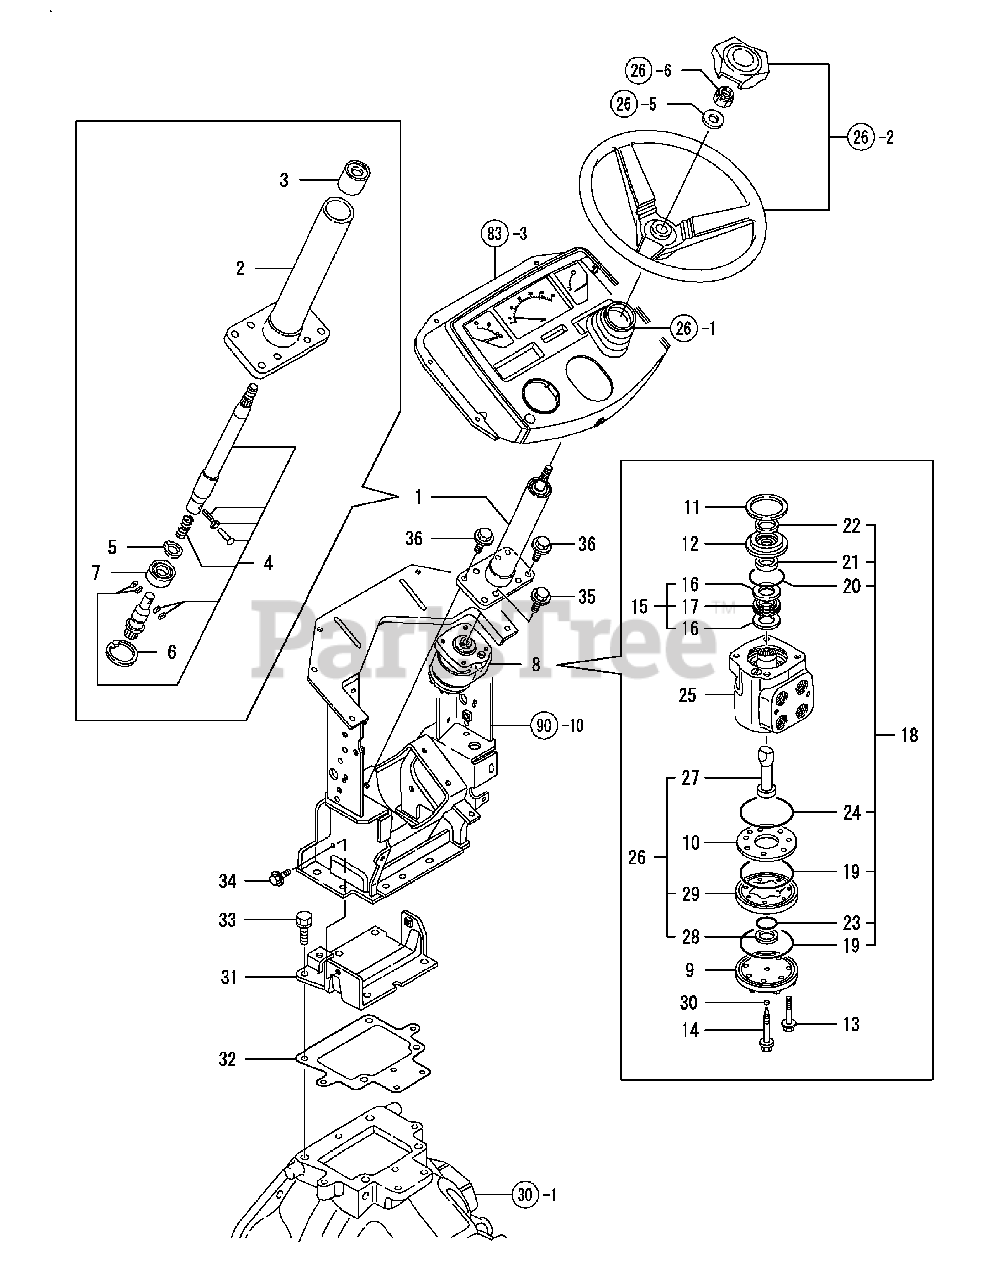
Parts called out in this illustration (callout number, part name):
1	COLUMN, STEERING
8	VALVE ASSY, STEERING
15	BEARING COMP.,NEEDLE
16	BEARING
23	SEAL
25	VALVE ASSY, CONTROL
26	DRIVE COMP.,DIROTOR
32	PACKING,CLUTCH C
33	BOLT W/WASHER M12X20
34	BOLT M 8X 16 PLATED
35	BOLT M10X 25 PLATED
36	BOLT M10X 25 PLATED
